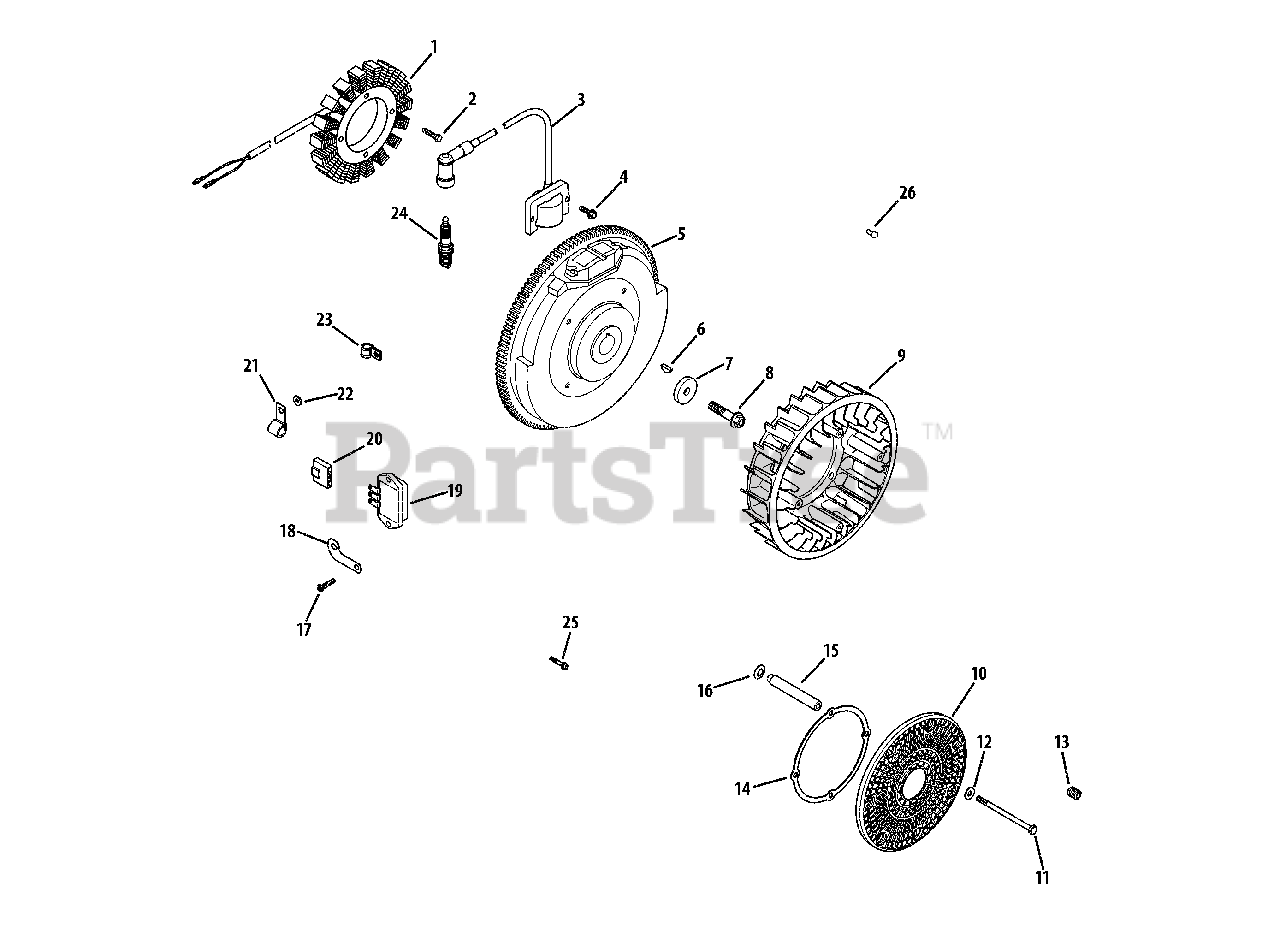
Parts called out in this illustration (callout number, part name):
1	15/20 Amp Stator Kit
2	Thread Forming Screw
3	Module Ignition Key (CDI Fixed)
4	Thread Forming Screw
6	Key, 3/16 x 5/8
7	Flat Washer, 13/32
8	Flange Screw, M10 x 1.5 x 45
9	Fan
11	Cap Screw, M6 x 1.0 x 99.5
12	Flat Washer, 1/4 x 5/8
13	Set Screw, #10-24 X 1/4
14	Support Ring
16	Spring Washer, 10 MM
17	Hex Flange Hi-Lo Screw
18	Ground Strap Bracket
19	Regulator/Rectifi er
21	Cable Clip
22	Flat Washer, 1/4 x 1/2
24	Spark Plug (Std.)
25	Flange Screw, M8 x 1.25 x 45
26	Washer Head Tap Screw, #8-18 x 1/2
